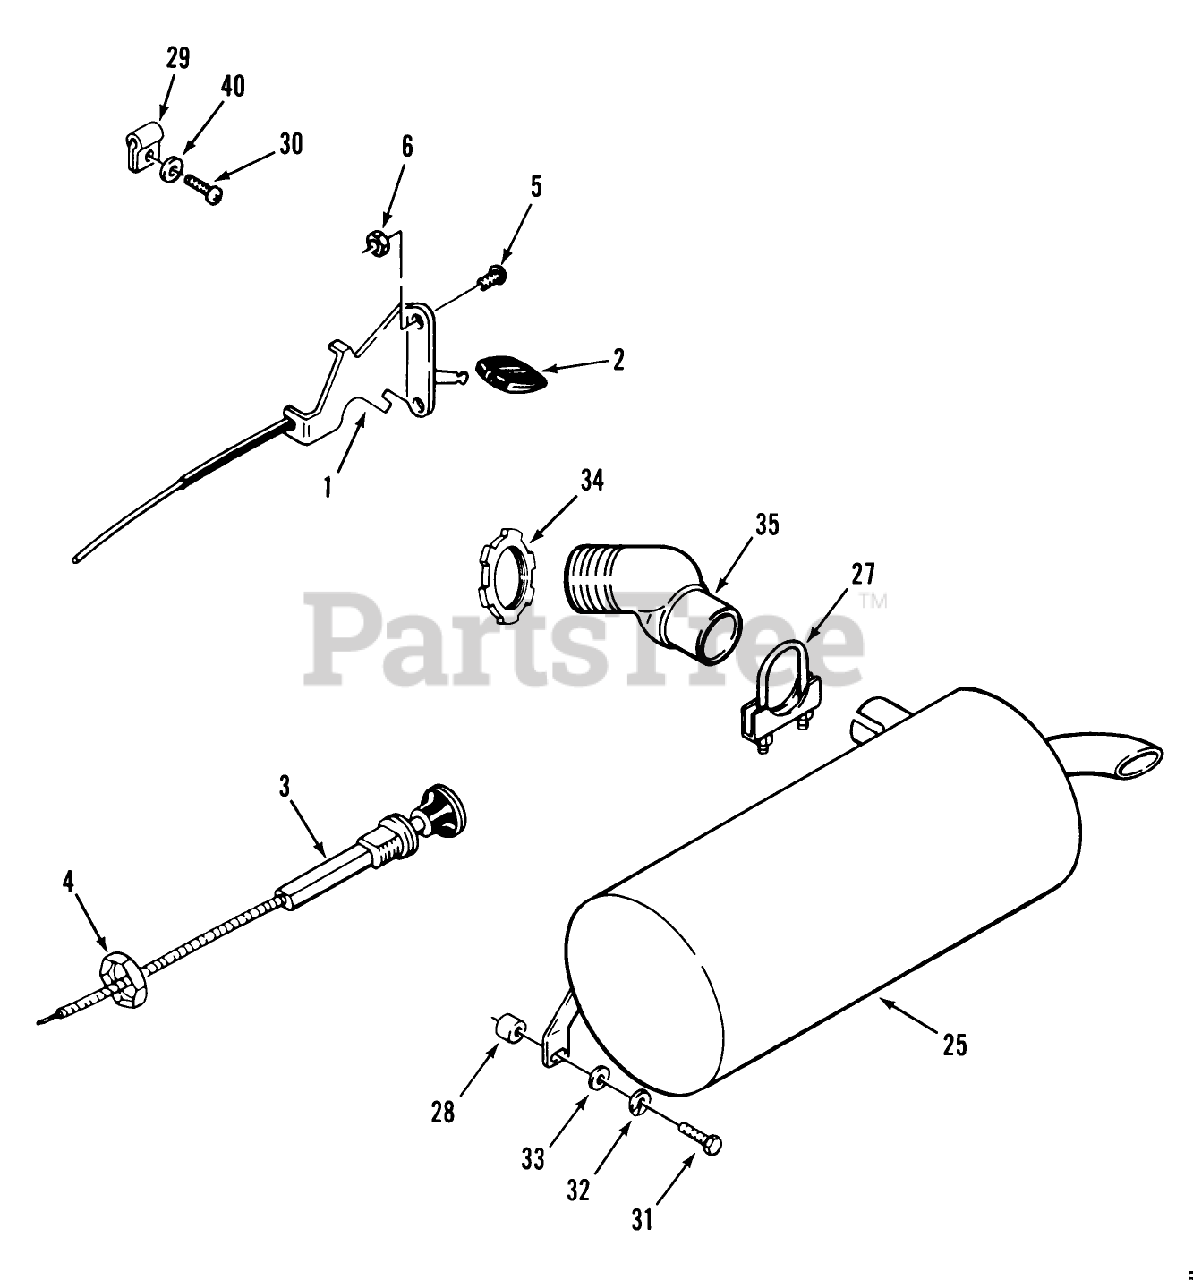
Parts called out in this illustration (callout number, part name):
1	CONTROL-THROTTLE
2	KNOB-THROTTLE
3	CONTROL CHOKE
3	CONTROL-CHOKE
4	NUT-HEX PALNUT
5	SCREW-PPH
28	SPACER
29	KOHLER 48-154-01
30	KOHLER X-67-83
33	WASHER 5/16 SAE
34	KOHLER AC-1536
35	KOHLER47-054-01
40	KOHLER X-25-72
